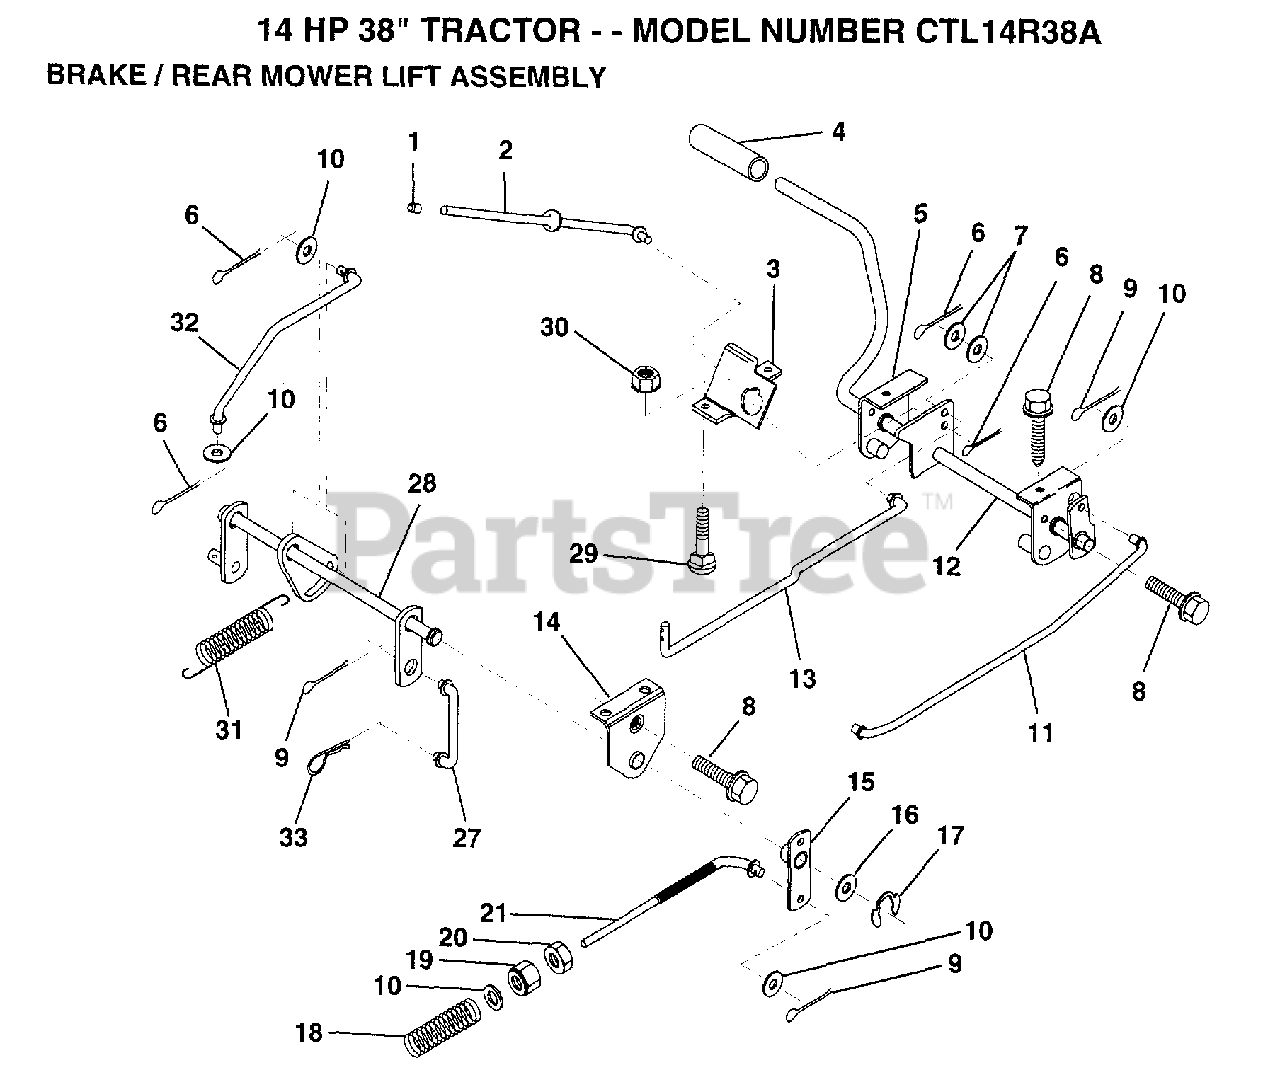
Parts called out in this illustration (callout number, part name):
2	"ROD,PARK BRAKE"
3	"BRKT,PARK BRAKE"
4	PEDAL COVER T
5	BRK ASM CLUT LH
7	WASHER
8	SCREW LT
9	COTTER PIN
10	WASHER
11	"ROD,FRT BRAKE"
12	PEDAL ASM CLU/BRK
13	"ROD,CLUTCH"
14	"BRKT,LIFT SHAFT"
15	PVT BRAKE ARM ASM
16	WASHER T
17	KLIP RING
18	SPRING ROD LT
19	NUT
20	NUT
27	LINK LIFT REAR LR
28	LIFT.ASM.REAR.LR
31	COUNTER SPRING
32	LINK LIFT LEVER
